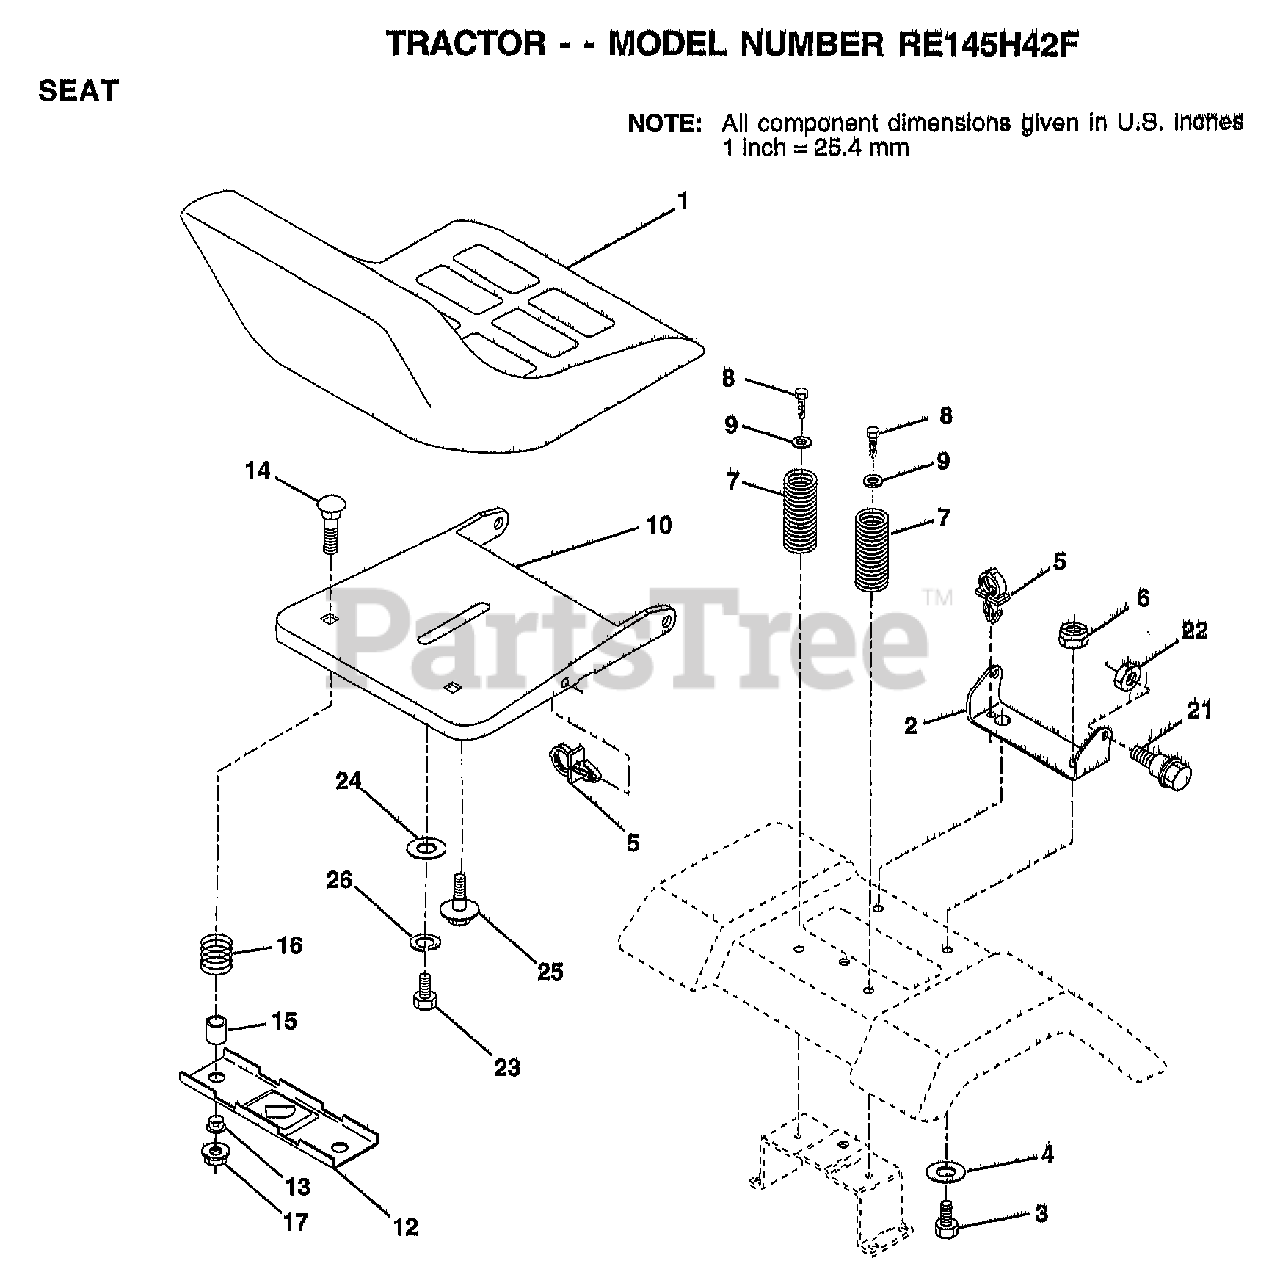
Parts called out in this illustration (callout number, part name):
2	BRACKET PVT SEAT
3	BOLT
4	WASHER PM
5	CLIP.PUSH-IN.HING
6	NUT
7	SPRING COMPRESSIO
8	SCREW
9	WASHER
10	PAN-SEAT
12	BRKT SWITCH
13	BUSHING
14	BOLT-RD HD SQ NK
15	SPLIT SPACER
16	SPRING
21	"BOLT,SHOULDER"
22	NUT
23	BOLT
24	WASHER
25	"BOLT,SHOULDER"
26	LOCKWASHER
